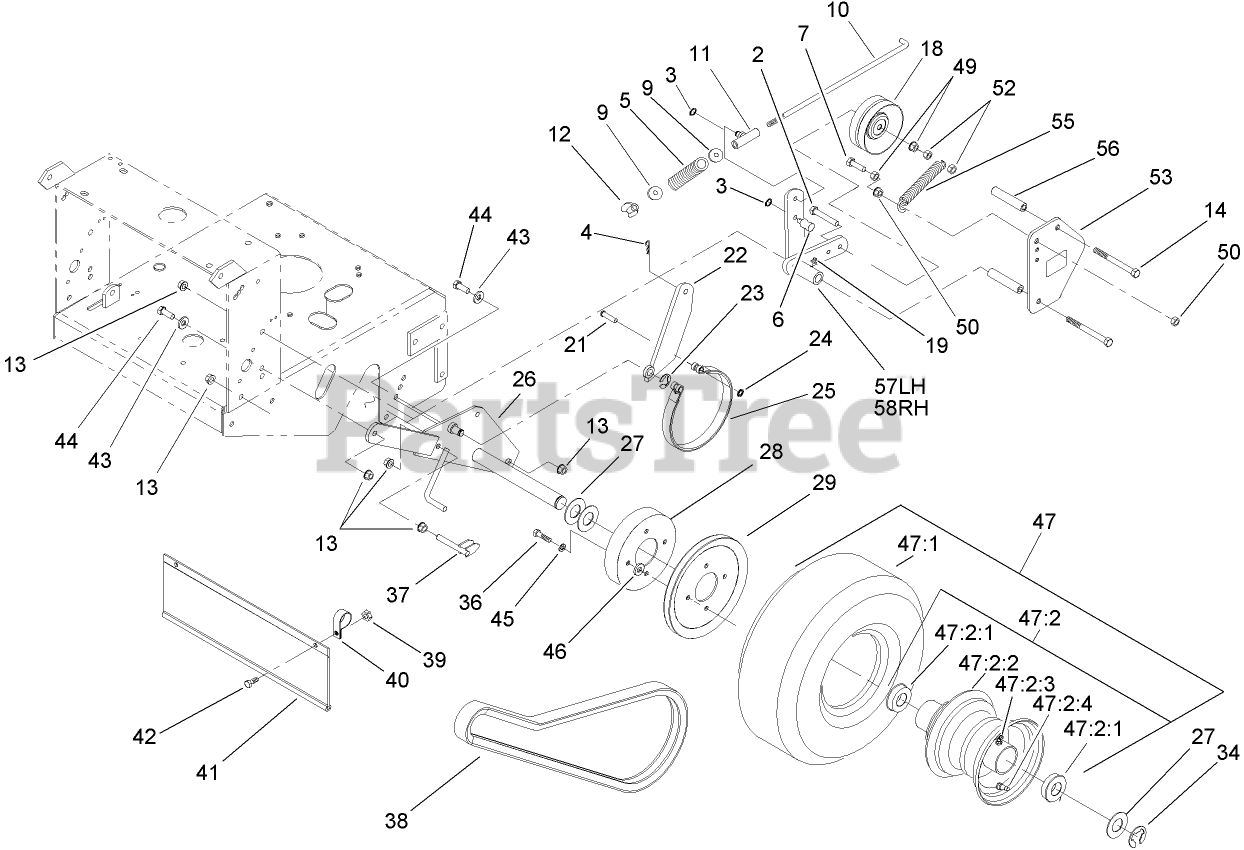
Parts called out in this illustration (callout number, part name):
2	SCREW-HH
3	RING-RETAINING
4	PIN-COTTER
5	SPRING-COMPRESSION
6	Swivel-Lever, Drive
7	SCREW-HH
9	WASHER-PLAIN
10	Linkage-Brake
11	SWIVEL-BRAKE
12	WINGNUT-NYLOCK
13	NUT-HHF, WHIZ
14	SCREW-HH
18	IDLER-WHEEL, DRIVE
19	FITTING-GREASE
21	PIN-CLEVIS
22	ARM-BRAKE
23	RING-RETAINING, EXTERNAL
24	NUT-PUSH
25	BAND-BRAKE
27	WASHER-SPACER
28	DRUM-BRAKE
29	SHEAVE-WHEEL, DRIVE
34	RING-SNAP
36	SCREW-HH
37	Scraper
38	BELT-DRIVE, WHEEL
39	NUT-LOCK, NI
40	CLAMP-R
41	SHIELD-TRAILING
42	SCREW-HH
43	WASHER-BELLEVILLE
44	SCREW-HH
45	WASHER
46	WASHER-LOCK
47	WHEEL AND TIRE ASM
47:2	WHEEL AND HUB ASM
47:2:1	BEARING-FLANGED
47:2:2	Rim ASM
47:2:3	Fitting-Grease
47:2:4	Valve Stem and Cap
49	NUT-HHF, WHIZ
50	NUT-HF
52	NUT-LOCK, NI
53	Shield-Wheel, Drive
55	SPRING-EXTENSION
56	SPACER,SHIELD
57	Arm-Idler, LH
58	Arm-Idler, RH
